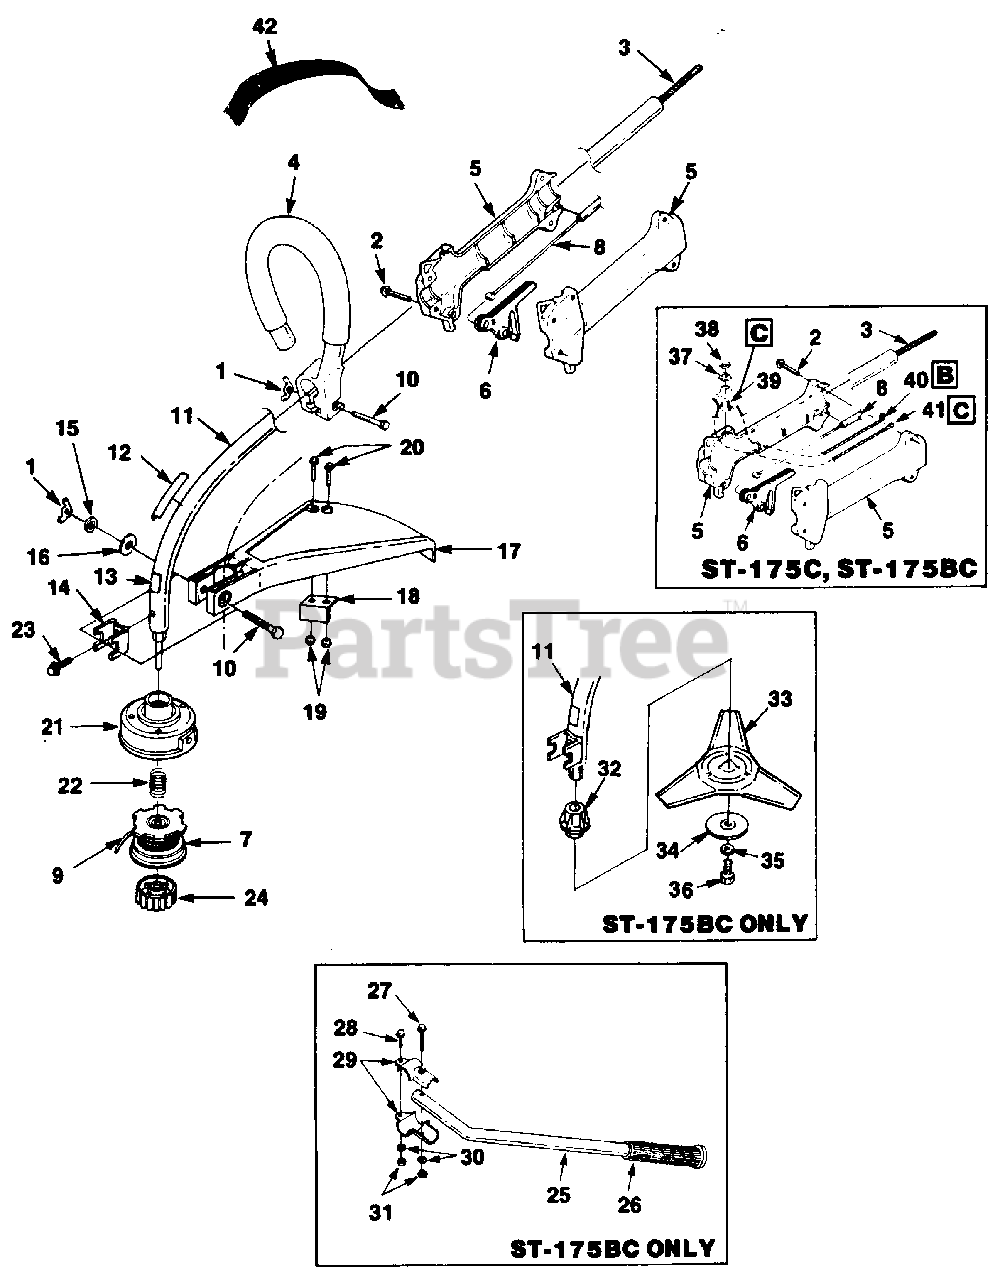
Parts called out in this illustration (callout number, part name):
1	NUT- Wing
2	SCREW- Plastite (#8 x 3/4")
3	SHAFT- Flexible
4	HANDLE- Front
5	HANDLE GRIP ASSEMBLY
6	TRIGGER
7	SPOOL & STRING (ST-155) (Dual Line)
8	CABLE-Throttle
9	LINE- Replacement (.080 Dia.) (100 Ft.)
10	SCREW (10-24 x 2")
11	HOUSING- Drive Shaft
12	DECAL- Starting Instructions
13	DECAL- Warning
14	CLAMP
15	LOCKWASHER (1/4")
16	WASHER- Flat (1/4")
17	DEFLECTOR- Grass
18	BLADE- Cut-off (Models 145 & 155)
19	NUT (10-24)
20	SCREW (10-24 x 7/8")
21	HOUSING & EYELET- Dual line
22	SPRING- Compression
23	SCREW (10-24 x 3/8")
24	RETAINER- Spool (R.H. Threaded)
25	HANDLE BAR (ST-175BC)
26	GRIP (ST-175BC)
27	SCREW (ST-175BC)
28	SCREW (ST-175BC)
29	CLAMP (ST-175BC)
30	WASHER (ST-175BC)
31	NUT (ST-175BC)
32	ADAPTOR (ST-175BC)
33	BLADE- Weed (ST-175BC)
34	WASHER- Cupped (ST-175BC)
35	WASHER (ST-175BC)
36	SCREW (ST-175BC)
37	PLATE- Indicating (ST-175C & ST-175BC)
38	NUT (ST-175C & ST-175BC)
39	SWITCH- Toggle (ST-175C & ST-175BC)
40	LEAD- Electrical (ST-175C & ST-175BC)
41	LEAD- Ground (ST-175C & ST-175BC)
42	HARNESS w/connector (GST & ST-175BC)
